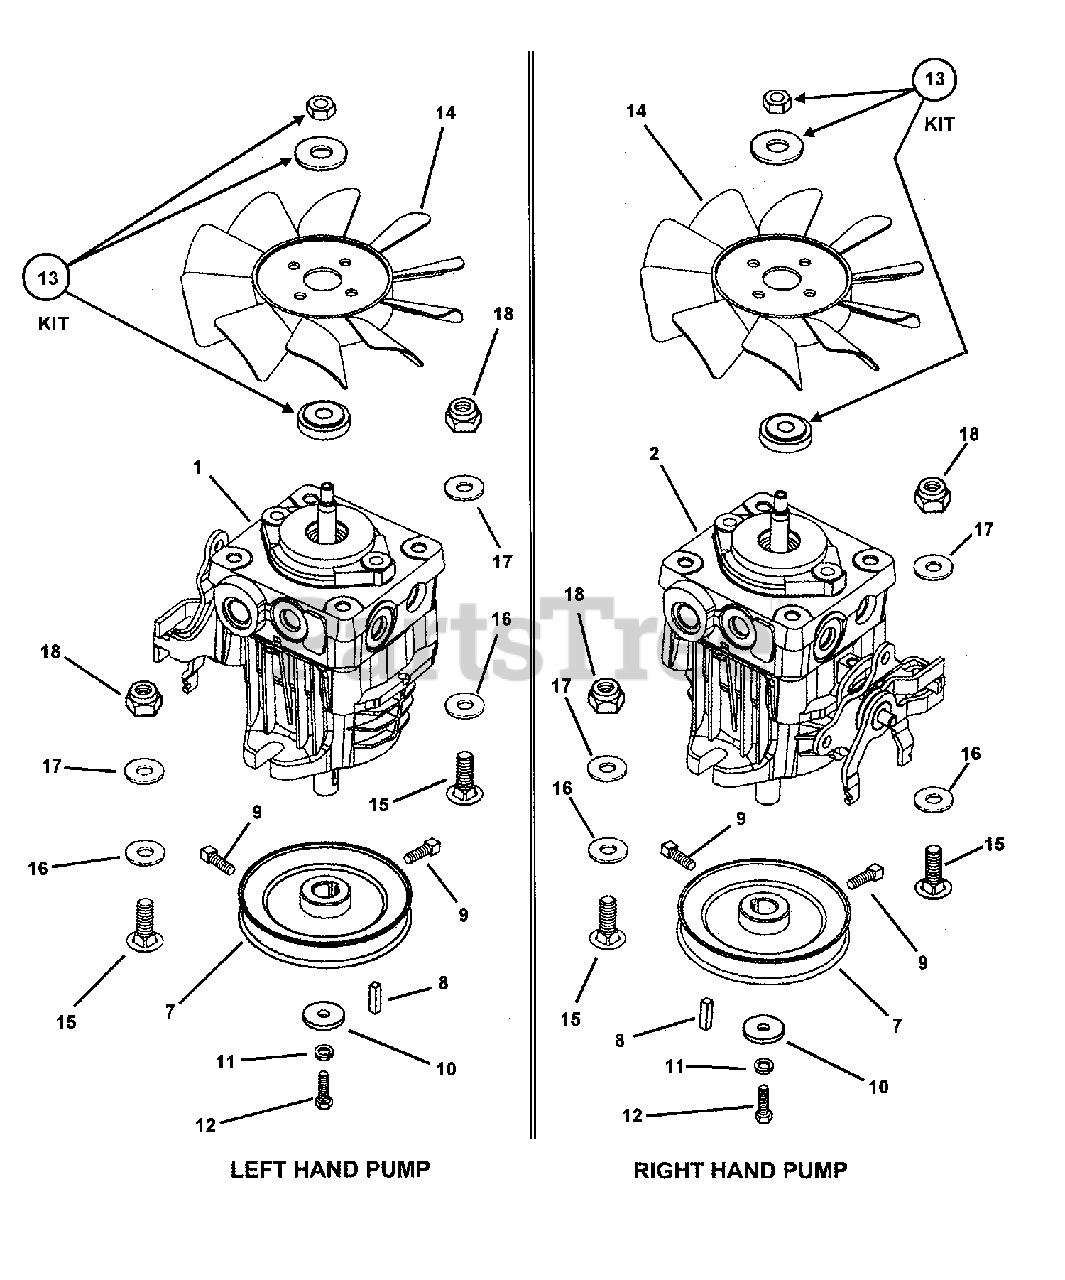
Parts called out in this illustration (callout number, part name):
1	PUMP, Hydro-Gear (BDP-10A-314) Left Hand
1	PUMP, Hydro-Gear (BDP-10A-331) Left Hand
2	PUMP, Hydro-Gear (BDP-10A-424) Right Hand
2	PUMP, Hydro-Gear (BDP-10A-454) Right Hand
7	PULLEY, Hydro Drive Pump
8	KEY, M5 x M20
9	SCREW, 1/4-20 x 1/2" Square Head Set w/Patch Lock
10	WASHER, .281 x 1.00 x .125 Flat
11	WASHER, 1/4" Split Lock
12	SCREW, M6 1.0X12MM, Hex Head, CZ
13	HUB KIT for BDP-10A Pump w/Thru Shaft (Incl. indented items below)
14	FAN, 7" Nylon, Counter-Clockwise
15	BOLT, 3/8-16 x 1-1/4" Short Neck Carriage GR5
16	RETAINER, 3/8" Bolt
17	WASHER, 3/8" Flat
18	NUT, 3/8-16 HEX NYLON LOCK
